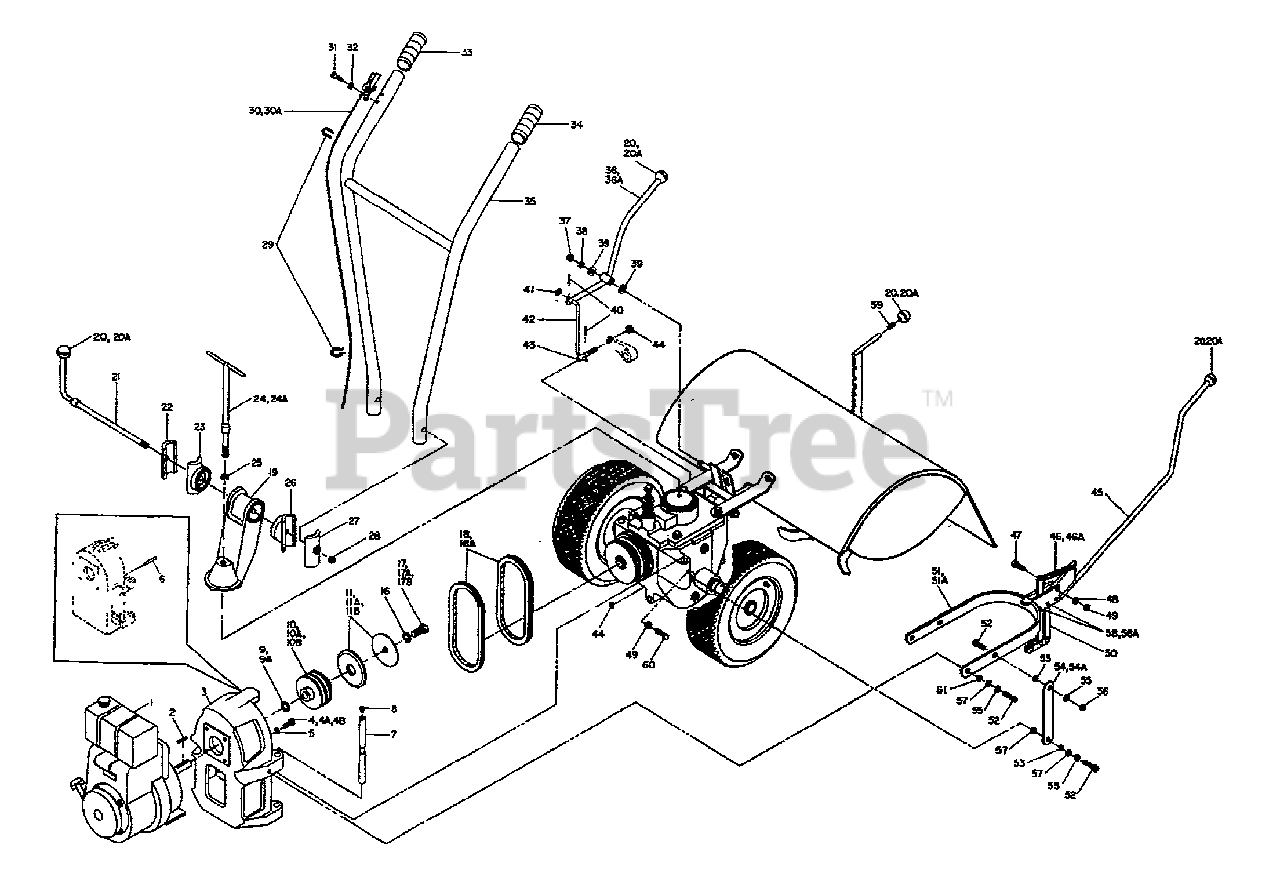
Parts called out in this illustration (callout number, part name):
1	ENGINE
2	KEY-.188 SQ X 2.33
3	MOUNT-MOTOR ENG.HSE I,II,III
4	SCR 5/16-24 X 1
4A	SCR-HH 5/16-18X1.0 G5 ZP
4B	SCR 5/16-24 X 1
5	WASHER-LK .312 ZP
6	PIN-SPIROL .25 X 2.5
7	BAR-ENG MTG W/CAP PLUG
8	PLUG-CAP (RED)
9	SHIM-1.0X.7656X.062
9	SHIM-1.0X.7656X.031
9A	SHIM-1.0X.7656X.062
10	PULLEY-ENG MACH
10A	PULLEY-ENG MACH D/BELT
10B	KIT-PULLEY CONVERSION
11	KIT-ADJ BLOCK/REV DISC
11A	KIT-REV DISC 2 SPEED
11B	KIT-REV DISC 2 SPEED
16	WASHER-LK .375 @ DEPL
17	SCR-HH 3/8-24X1.75 ZP
17A	SCR-HH 3/8-24X1.5 G5
17B	BOLT-HH 5/16-24 X 1.5 ZP
18	BELT-V
18A	KIT-V BELT
19	KIT-BASE ASSM
20	KNOB-CONTROL
20A	KNOB-THREADED
21	STUD-H/BAR W/NUT & RING
22	CLAMP-RH HORSE 1021-2
23	RATCHET-RT H/BAR CAST
24	T-CLAMP WELD
24A	SCR-5/8 (2373/1043)
25	WASHER-LK .625 ZP
26	RATCHET-LT H/BAR CAST
27	CLAMP-LH HORSE 1021-1
28	NUT-HEX JAM 1/2-13
29	TIE-RED
30	CABLE-THROTTLE
30A	CABLE-THROTTLE
31	SCR-PHS M10-32X.5 STH ZP
32	WASHER-LK M10
33	GRIP-H/BAR SMOOTH
34	GRIP-HANDLEBAR
35	ASSM-HANDLEBAR
36	LEVER-SPD SHIFT W/KNOB
36A	LEVER-WHL SPEED W/KNOB
37	NUT-H/LK 1/2-20 ZP
38	WASHER-LK .5
39	WASHER-PLAIN 1/2 ZP
40	PIN-COTTER .094X1.0
41	WASHER-FLAT 5/16 SAE
42	ROD-CONNECTING
43	SWIVEL
44	NUT-H/LK 5/16-18
45	TRAC-RER
46	SPRING-.436 X 3.25
46A	SPRING-.406 X 3.125
47	SCR-HH 5/16-18X1.25 G5ZP
48	WASHER-LK .312 ZP
49	NUT-HEX 5/16-18 ZP
50	KIT-ROLLER HORSE 1 & 2
51	KIT-LEVER FWD/REV-HORSE 2
51A	YOKE-2SP WELD PNT
52	SCR-HH 3/8-16X1.0 G5 ZP
53	BUSHING-.5X.375X.3
54	BAR-CLUTCH YOKE
54A	LINK-CLUTCH YOKE
55	WASHER-LK .375 @ DEPL
56	NUT-HEX 3/8-16 ZP
57	WASHER-FLAT 3/8 SAE
58	PIN-SPIROL .313 X 1.0
58A	TRACTOR-R.E.R. 11HP 36"
59	RING-TOLERANCE .5325 ID
60	SCR-HH 5/16-18X1.0 G5 ZP
61	BUSHING-.5X.375X.325
